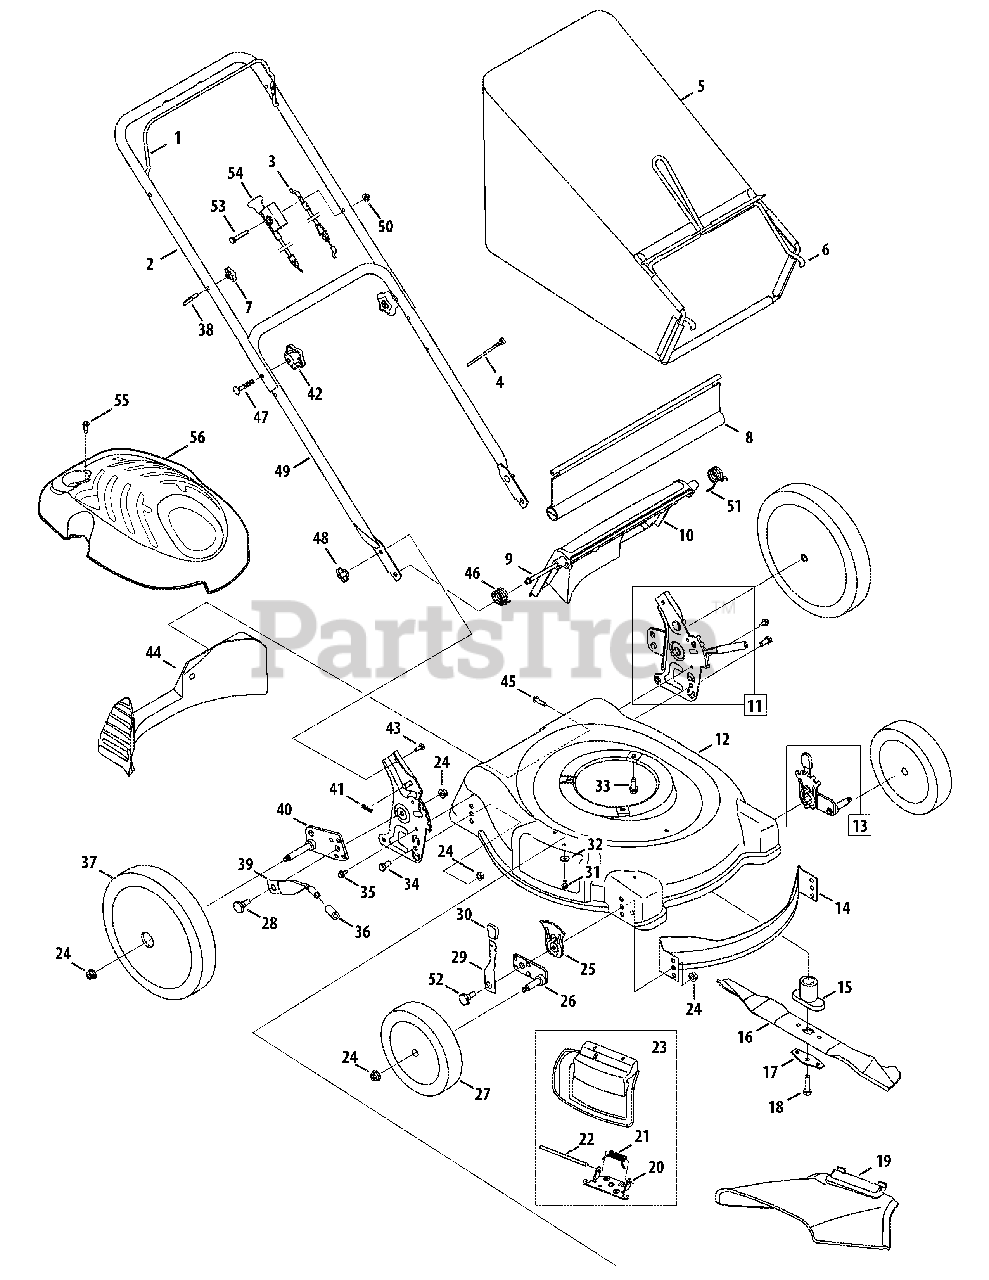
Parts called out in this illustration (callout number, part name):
3	Control Cable
4	Cable Tie
5	Grass Bag
7	Handle Knob
8	Trailshield
9	Pivot Rod
10	Rear Discharge Door
11	Rear Handle Bracket Assy. - LH
11	Rear Handle Bracket Assy. - RH
13	Front Hgt. Adj. Assy., 8" Whl. - RH
14	Front Baffle
15	Blade Adapter w/Star
16	21-inch Mulching Blade
17	Bell Blade Support
18	Hex Screw, 3/8-24 x 2.5
19	Side Discharge Chute
20	Deflector Chute Adaptor
21	Torsion Spring
22	Hinge Pin
23	Mulch Plug Assembly
24	Flange Lock Nut 3/8-16
25	Height Adjustment Plate
26	Pivot Arm Assy RH (8" wheel)
26	Pivot Arm Assy LH (8" wheel)
27	Front Wheel, 8 x 1.8, Bar
28	Shoulder Scr., .5D x .385
29	Front Spring Lever
30	Height Adjust Knob
31	TT Screw, 1/4-20 x .500
32	Bell Washer
33	TT Screw, 3/8-16 x 1.0
34	Hex Screw, 3/8-16 x .75
35	TT Screw, 1/4-20 x .625
36	Foam Grip
37	Rear Wheel, 12 x 1.8, Bar
38	Eye Bolt
39	Rear Hi-Wheel Spring Lever
40	Rear Pivot Arm Assy - RH
40	Rear Pivot Arm Assy - LH
41	Hairpin Clip
42	Star Knob
43	Carriage Bolt ,1/4-20 x .75
44	Rear Baffle
45	Screw HL, 1/4-15 x 1.00
46	Torsion Spring - RH
47	Carriage Bolt, 5/16-18 x 2
48	Wing Nut
50	Nut, Flange Lock, 1/4-20
51	Torsion Spring - LH
52	Shoulder Screw, .5 D x .385 - Front
53	Screw, 1/4-20 x 1.50
54	Choke Cable
55	Screw, Machine, M4-.7
56	Engine Shroud - 1P65 Engine
56	Engine Shroud - 1P70 Engine
